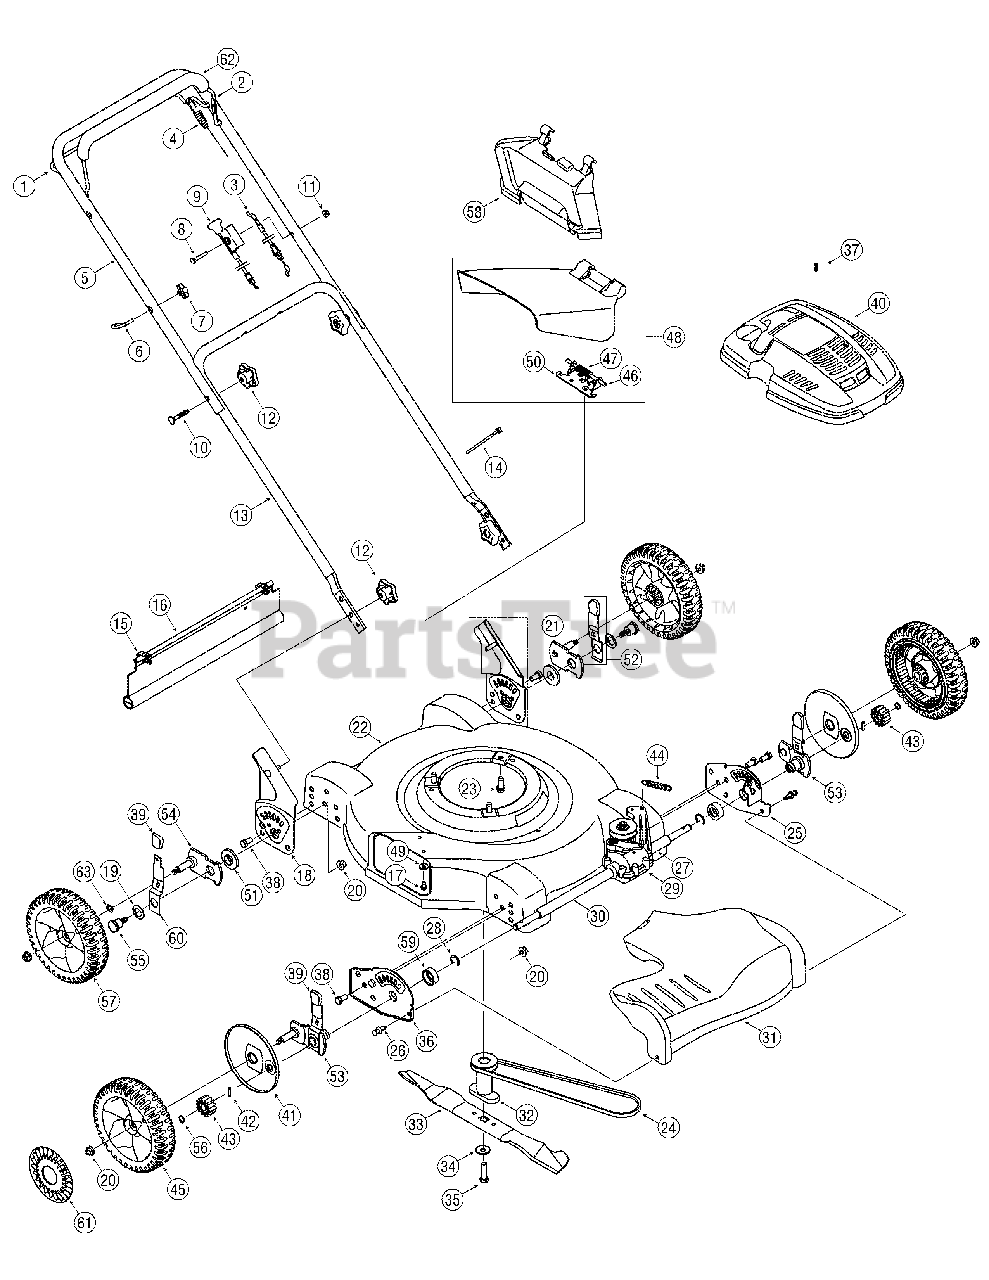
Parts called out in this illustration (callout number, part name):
1	Drive Control
3	Blade Control Cable
4	Drive Control Cable
6	Eye Bolt
7	Wing Nut, 1/4-20
8	Hex Screw, 1/4-20 x 1.50
9	Choke Cable
10	Carriage Bolt, 5/16-18 x 2.0
11	Flange Lock Nut, 1/4-20
12	Star Knob
14	Cable Tie
15	Hinge Clip
16	Trail Shield
17	Hex Screw, 1/4-20 x.500
20	Lock Nut, 3/8-16
23	Hex Washer Scr., 3/8-16 x 1.0
24	V-Belt, 3L x 32.90
26	Rivet
27	Sleeve Spacer, .550 ID x 2.22
28	Retainer Ring
29	Transmission Assy. Comp.
30	Sleeve Spacer, .550 ID x 8.51
31	Transmission Cover (Yellow)
31	Transmission Cover
32	Blade Adapter
33	22" Mulching Blade
34	Washer, Bell, .396 x 1.140 x .095
35	Hex Cap Screw, 3/8-24 x 1.5
37	Machine Screw, M4X.7
38	Hex Cap Screw, 3/8-16 x.75
39	Adjustment Knob
40	Engine Shroud (Yellow)
40	Engine Shroud (Black)
41	Wheel Dust Cover
42	Pin
43	Spur Gear 14T - RH
43	Spur Gear 14T - LH
44	Ext. Spring, .47 OD x 2.50
45	Front Wheel, 8 x 1.8
45	Front Wheel, 8 x 2.125
46	Hinge Pin
47	Torsion Spring
48	Side Discharge Assembly
49	Bell Washer, .265 ID x.75 OD
50	Deflector Chute Adapter
51	Height Adjustment Bearing
52	Rear Hgt. Adj. Lever Assembly
53	Front Lever Assembly
54	Rear Pivot Arm Assembly
55	Shoulder Screw, 3/8-16
56	Screw 1/4-20 X .39
57	Rear Wheel, 8 x 1.8
57	Rear Wheel, 8 x 2.125
58	Mulching Baffle
59	Bearing Support Spacer
60	Spring Lever
61	Hub Cap
62	Deluxe Bail Cover
63	Washer, Wave, .510 x .750 x .017
